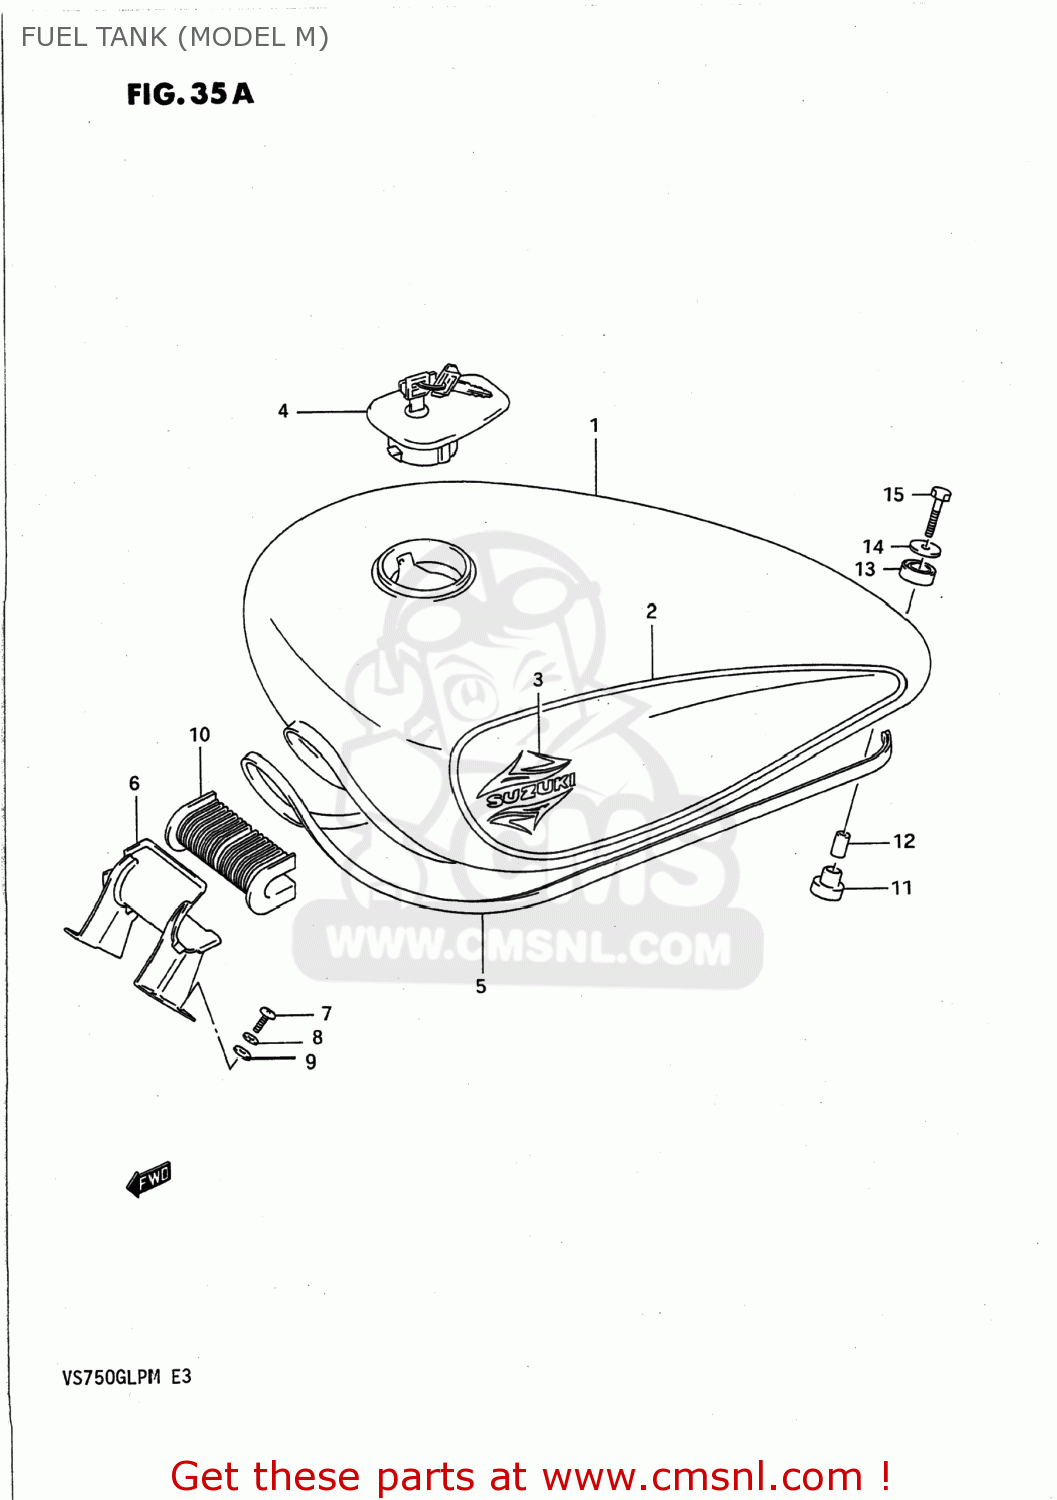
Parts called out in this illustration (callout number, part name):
1	TANK ASSEMBLY,FUEL
2	TAPE SET,FUEL TANK
3	EMBLEM,FUEL TANK
4	CAP SET,FUEL TANK
5	MOLDING,FUEL TANK
6	BRACKET COMP,FUEL TANK
7	SCREW
8	WASHER,LOCK
9	WASHER
10	CUSHION,FUEL TANK FR
11	CUSHION
12	SPACER (6.4X9X21.5)
13	CUSHION
14	WASHER (6.5X24X1.6)
15	SCREW
